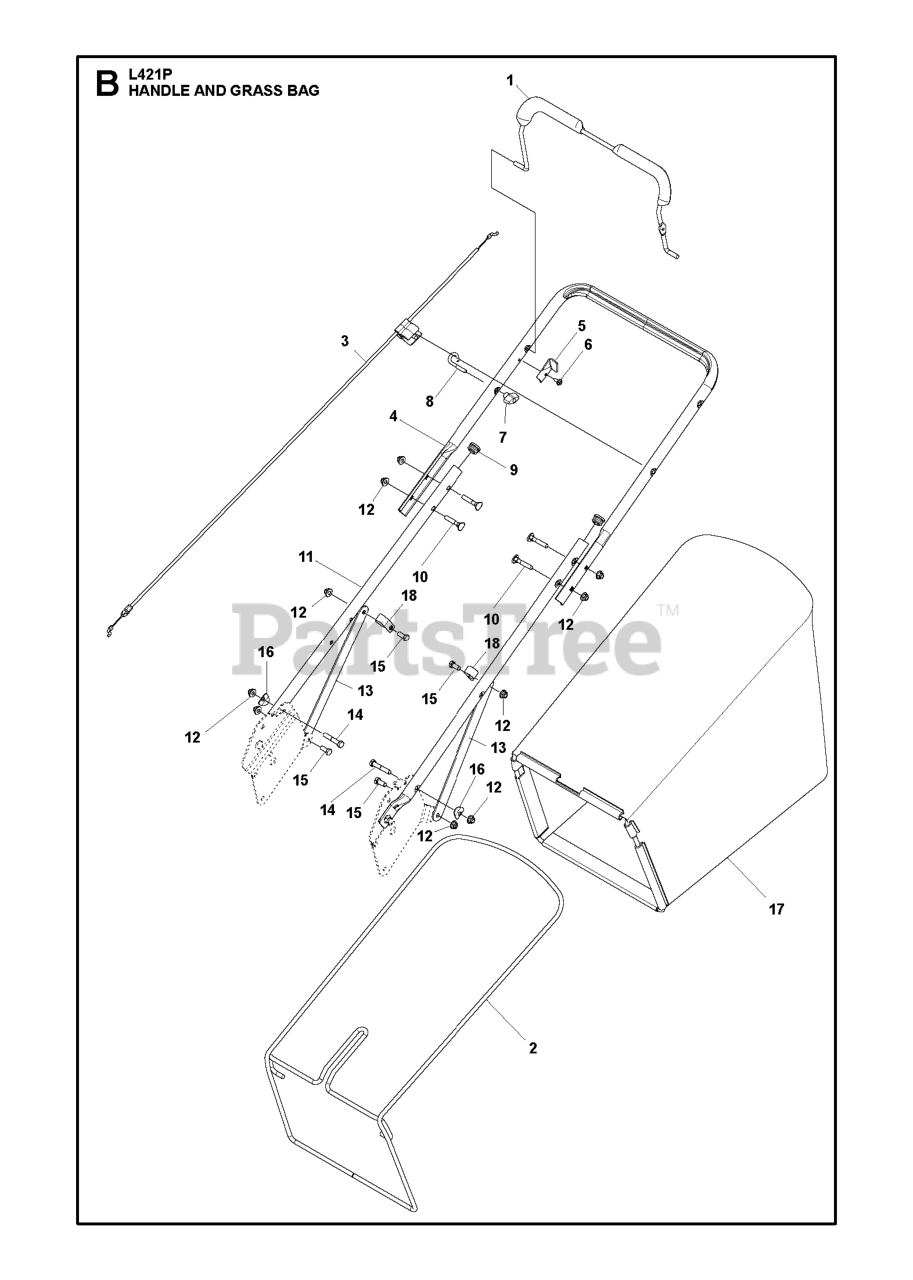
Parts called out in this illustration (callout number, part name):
1	BAIL.ARM.ASSY:STRAIGHT OM
2	FRAME.GBAG.AWD.21.BLACK
3	RP.CABLE.MZR.RGD.PLUS.STRT
4	HANDLEBAR UPPER, DST, EXT CRUS
5	BRACKET.UPSTOP.RT
6	SCREW
7	T-KNOB.NEW ROPE GUIDE
8	GUIDE.ROPE.BLK.ZINC.CHROM
9	PLUG.PLASTIC.7/8".14-20.GAUGE
10	BOLT, HANDLE 5/16-18X1.75
11	HANDLE LOWER, 21 COMMERCIAL GR
12	NUTNYLOK.FLRANGE.5/16-18
13	BRACE DIAGONAL HANDLE, 21 COMM
14	SCREW
15	BOLT HEXAGON HEAD 5/16-18"X3/4
16	WASHER CURVED 5/16"X1"X0.06" S
17	GBAG.C361029ER.HUSQ.GRY.21EFF
18	CLAMP LOOP, 7/8, 21 COMMERCIAL
